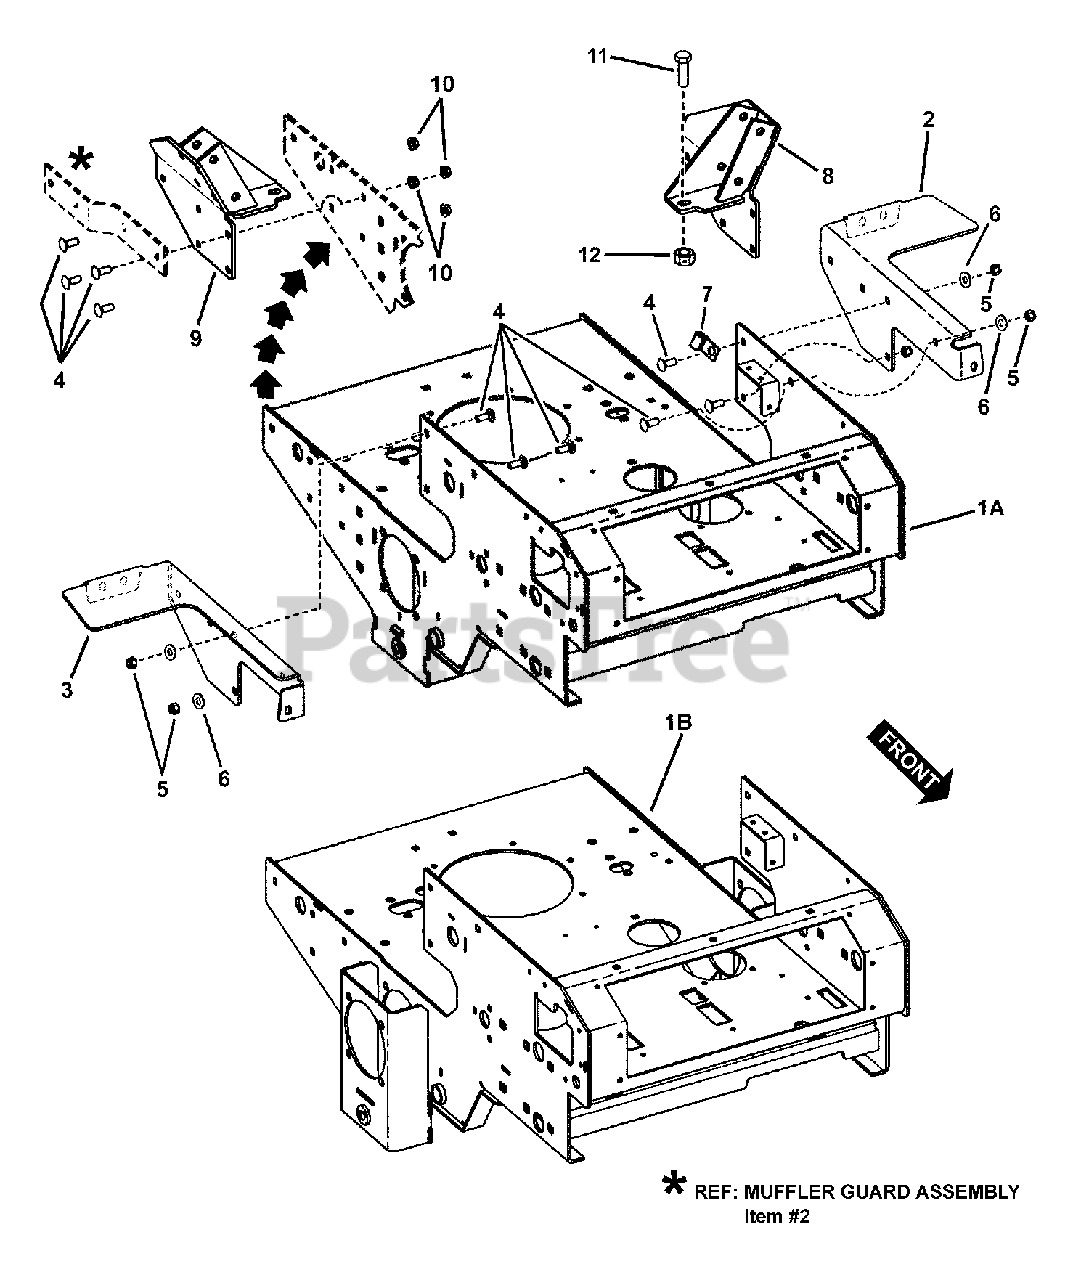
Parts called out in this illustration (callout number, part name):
1A	WELDMENT, Rear Frame (52" Deck)
1B	WELDMENT, Rear Frame (61" Deck)
2	WELDMENT, Left Hand Fuel Tank Bracket
3	WELDMENT, Right Hand Fuel Tank Bracket
4	BOLT, 3/8-16 x 1" Square Neck Carriage GR 5
5	NUT, 3/8-16 HEX NYLON LOCK
6	WASHER, 3/8" Flat
7	CLIP, Open 3/8" Cushioned
8	WELDMENT, Right Hand Socket
9	WELDMENT, Left Hand Socket
10	NUT, 3/8-16 HEX SERRATED FLANGE
11	BOLT, 1/2-13 X 1-1/2 GD5 CZ
12	NUT, 1/2-13 HEX SIDE LOCK
